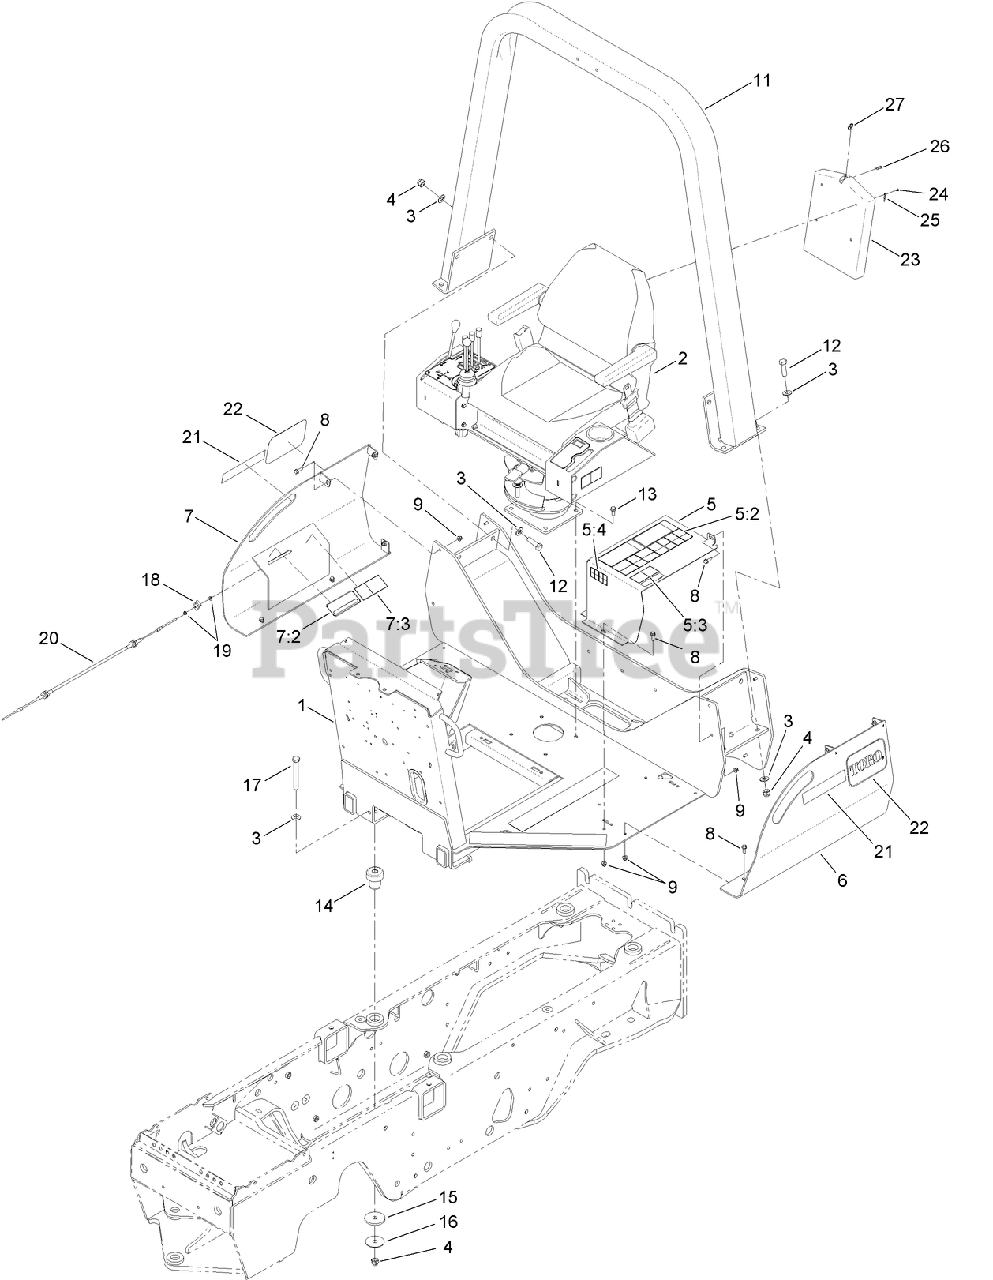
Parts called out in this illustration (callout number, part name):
1	PLATFORM-OPERATOR
2	SEAT ASM
3	WASHER-FLAT
4	NUT-LOCK, HEX
5	BATTERY COVER ASM
5:2	DECAL-SAFETY
5:3	DECAL-SAFETY
5:4	DECAL-WARNING, BATTERY
6	FENDER-LH
7	RH FENDER ASM
7:2	DECAL-REAR STEERING INDICATOR
7:3	DECAL-WARNING, STEERING
8	SCREW-HHF
9	NUT-LOCK, HHF
11	ROPS ASM
12	SCREW-HH
13	SCREW-HHF
14	MOUNT-REAR
15	WASHER-SNUBBING
16	WASHER
17	SCREW-HH
18	POINTER-INDICATOR, POSITION
19	NUT-KEPS
20	POSITION INDICATOR CABLE ASM
22	DECAL
23	HOLDER-MANUAL, OPERATOR
24	RIVET-POP
25	LANYARD
26	POST-MANUAL
27	STRAP-TIE, NYLON
